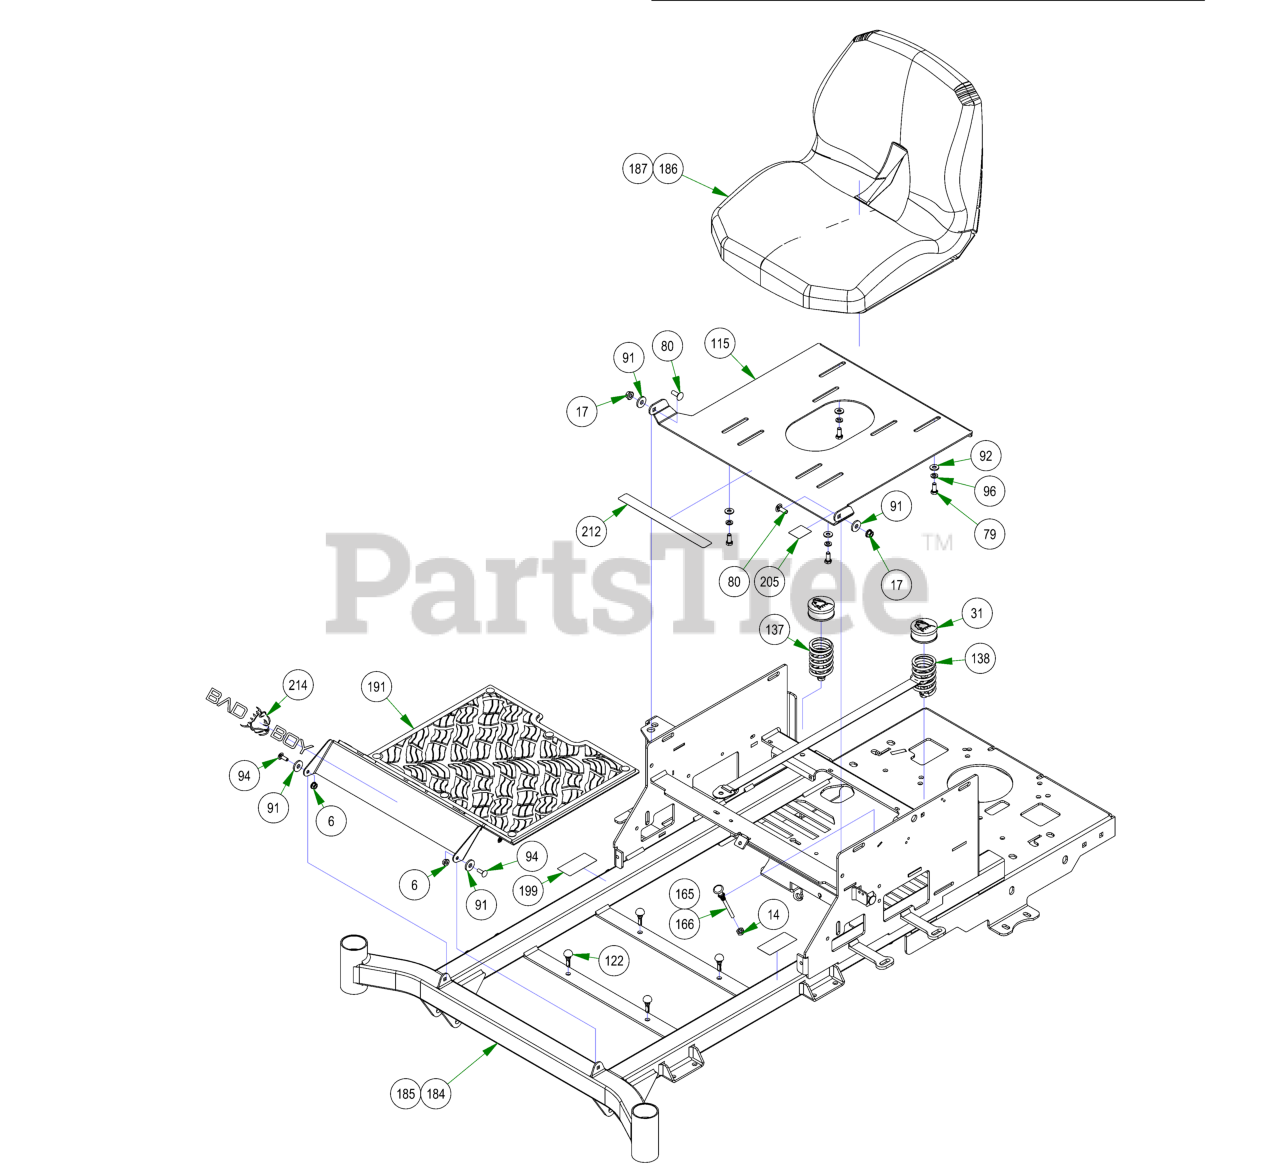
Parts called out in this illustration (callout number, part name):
6	1/4-20 NYL INSERT FLANGE LOCKNUT ZINC
14	3/8-24 HEX NUT ZINC YELLOW
17	5/16-18 NYLON INSERT FLANGE LOCKNUT ZINC
31	Spring Cap Cover
79	5/16-18 X 3/4 HEX CAP SCREW (GR.5) ZINC
80	5/16-18 X 7/8 CARRIAGE BOLT ZINC
91	.360 ID X .983 OD X .120 THICK FLAT WASHER NYLON
92	1/4 USS FLAT WASHER (3/4 OD) ZINC
94	1/4-20 X 3/4 CARRIAGE BOLT (GR.5) ZINC
96	5/16 SPLIT LOCKWASHER ZINC
115	2017 MZ Seat Plate
122	2023 Floor Board Rubber Bumper
137	Seat Spring Assembly
138	Seat Spring Assembly
184	2023 MZ 42-48 Frame - Painted
185	2023 MZ-Avenger 54-60 Frame - Painted
186	2019 Magnum Seat/Kohler
187	2022 Magnum Seat
191	2020 MZ AVEN Floorboard Assembly
199	2018 LH/RH Steering Control Decal Roll
205	2018 MZ/Magnum/ZT/MAV/Comp Out Brake Decal
212	Outlaw Warning Decal
214	Flying Bulldog Front Bumper Decal
